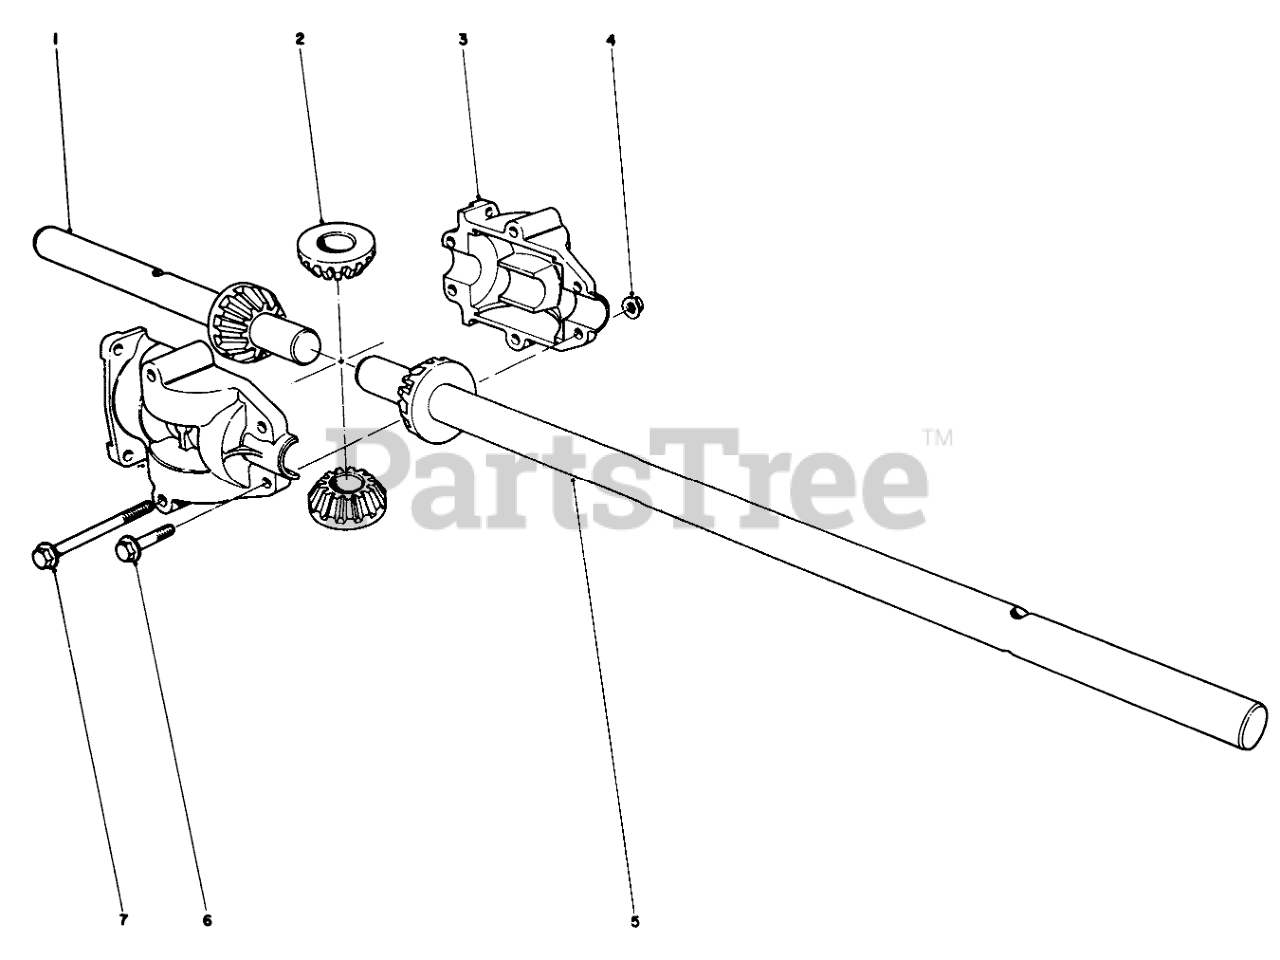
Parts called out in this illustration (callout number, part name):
1	Short Shaft
3	Housing Half
4	NUT-HHF
5	Long Shaft
